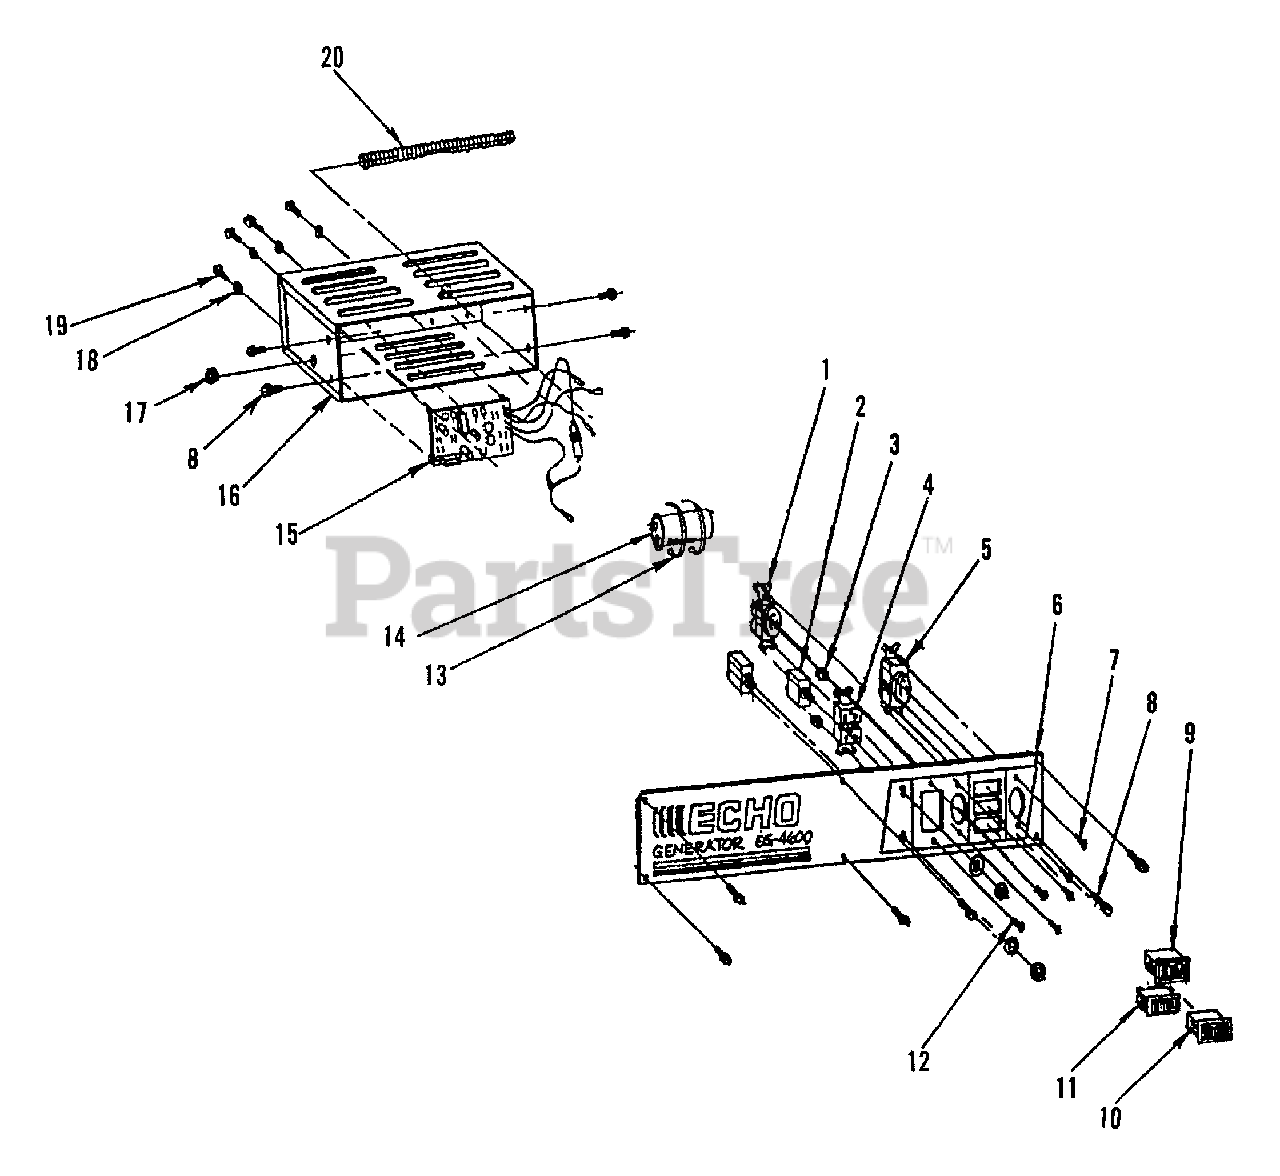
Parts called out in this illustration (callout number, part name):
1	LOCK, TWIST 20A/125V
2	BREAKER, CIRCUIT - 20A/250V
3	NUT - 8-32 -- KEPS
4	GFCI - 15A/125V
5	LOCK, TWIST 20A/240V
6	PANEL, SILK SCREENED
7	6-32×3/8 RHS
8	SCREW - 10-24
9	SWITCH, IGNITION
10	SWITCH, FULL POWER
11	SWITCH, ECHO-MISER
12	8-32×3/8 RHS
13	TIE, CABLE
14	CAPACITOR - 50UF 370V
15	CIRCUIT, ECHO-MIZER
16	BOX, CONTROL
17	GROMMET
18	WASHER, LOCK
19	6-32×1/4 RHS
20	CONDUIT PIPE
